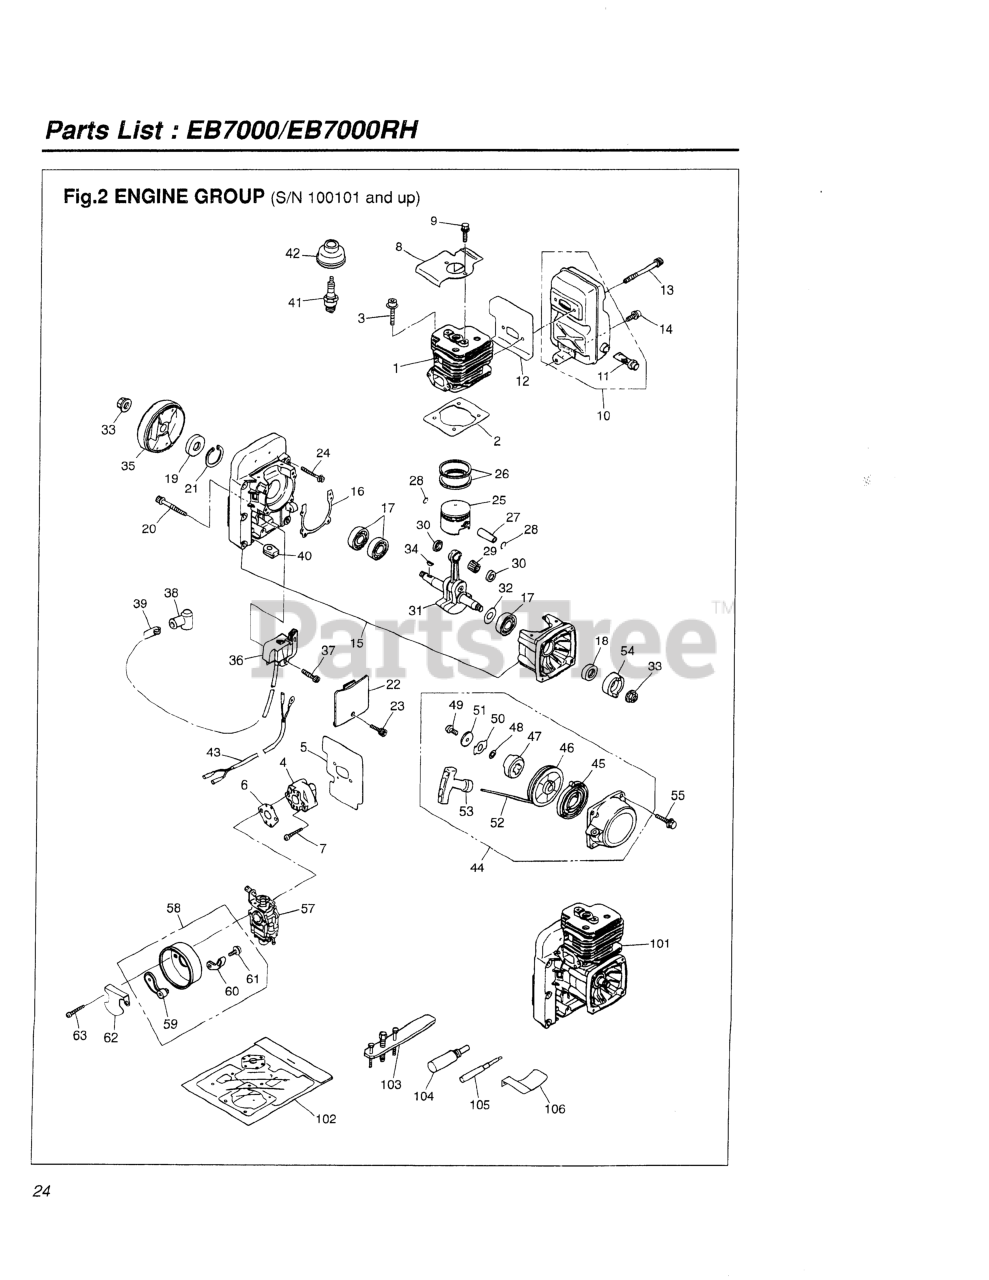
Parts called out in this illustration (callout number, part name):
2	GASKET, BASE
3	BOLT, M5 X 22
4	INSULATOR (REPLACES-13160)
5	GASKET
6	GASKET, CARB (RPLS -13131)
7	BOLT
8	COVER
9	BOLT, M5 x 10
11	ARRESTER
12	GASKET
13	BOLT, M6 X 70
14	BOLT, M6 X 12
15	CRANKCASE (RPLS. 2750-21100)
16	GASKET
17	BEARING (REPLACES 2810-21240)
18	SEAL, OIL 15 X 25 X 7
20	BOLT, M5 X 30
21	RING, SNAP, M35 X 1.5
22	COVER
23	BOLT, M4 X 16
24	BOLT, M6 X 40
25	PISTON
26	RING
27	PIN, PISTON
28	RING, SNAP
29	BEARING
30	WASHER (RPLS 1491-41510)
32	SHIM (REPLACES 848-870-G000)
33	NUT, M10
34	KEY
35	ROTOR (REPLACES -71110)
36	COIL ASSEMBLY, IGINITION
37	BOLT, M4 x 20
38	CAP
39	SPRING
40	GROMMET
42	CAP
43	CORD COMP.
44	RECOIL ASSY (RPLS -75100)
45	SPRING (RPLS -75220)
47	DOG
48	WASHER
49	SCREW
50	RETAINER (RPLS 1861-75161)
51	WASHER
52	ROPE
53	KNOB
54	PULLEY (RPLS -75210)
55	BOLT, M5 x 20
57	CARBURETOR (WYK-123-1)
58	CASE ASSY (RPLS -82400)
59	PLATE (RPLS -82420)
60	LEVER (RPLS -82430)
61	SCREW (RPLS- 82440)
62	PLATE
63	SCREW (RPLS 0263-30550)
102	KIT, GASKET
103	PULLER ASSY
104	STOPPER (TOOL) (RPLS 3320-9641
105	PULLER, PISTON PIN
